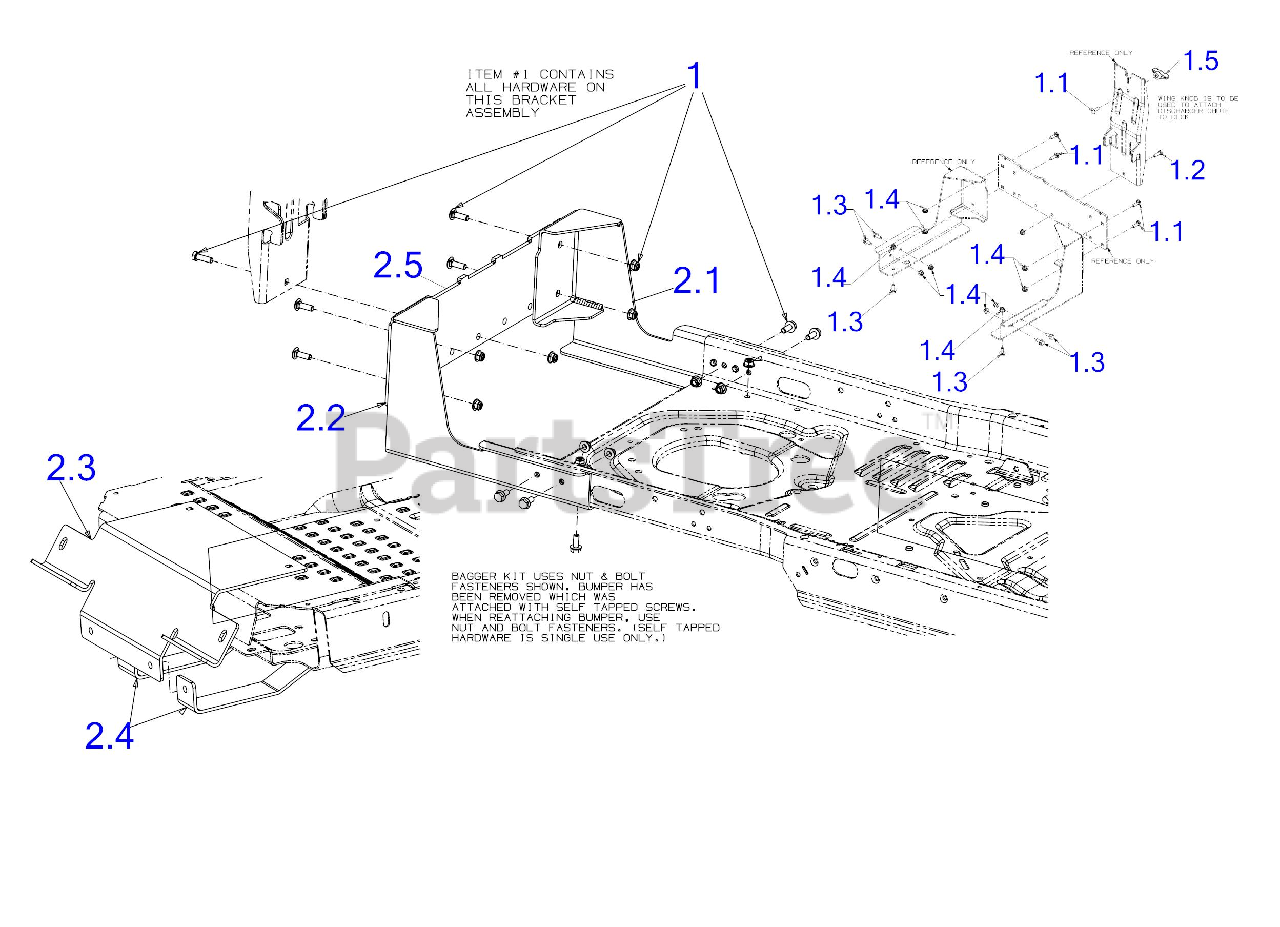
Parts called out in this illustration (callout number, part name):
1	HARDWARE PACK BAGGER MOUNTING
1.1	CARRIAGE BOLT 5/16-18 x 1.00
1.2	SCREW 5/16-18 x 1.0 GR5
1.3	SCREW 5/16-18
1.4	FLANGE LOCK NUT 5/16-18
1.5	WING KNOB 5/16-18
2.5	SUPPORT PLATE
